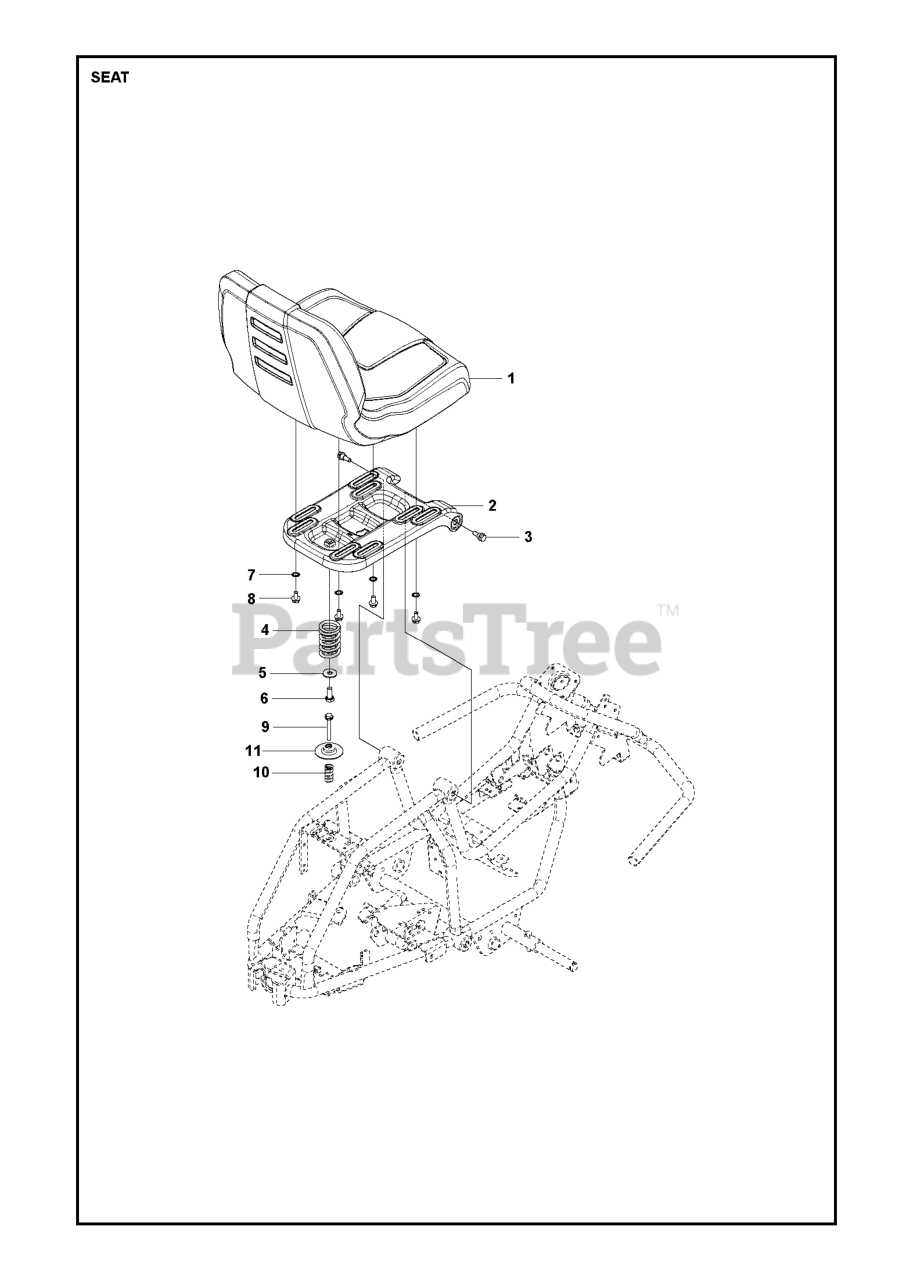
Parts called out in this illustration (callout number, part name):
2	SEAT BRACKET
4	SEAT SPRING
6	Screw M10x25
